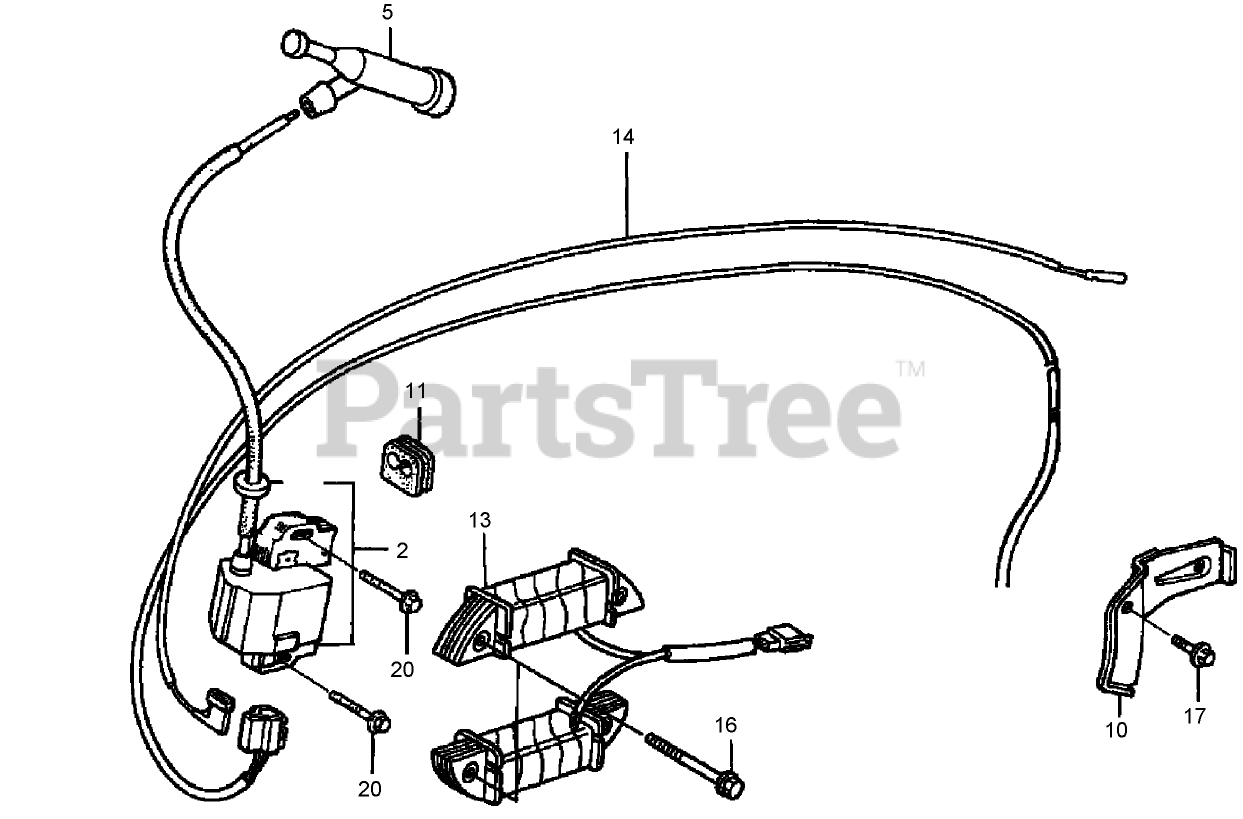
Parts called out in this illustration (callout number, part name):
2	COIL ASM-IGNITION
5	CAP ASM- NOISE SUPPRESSOR
10	CLAMP-WIRE
11	GROMMET-WIRE
13	COIL ASM-CHARGE (10A)
14	WIRE-STOP SWITCH (430MM)
16	BOLT-FLANGE (6X40)
17	BOLT-FLANGE (6X12) (C T200)
20	Bolt-Flange (6X28)
